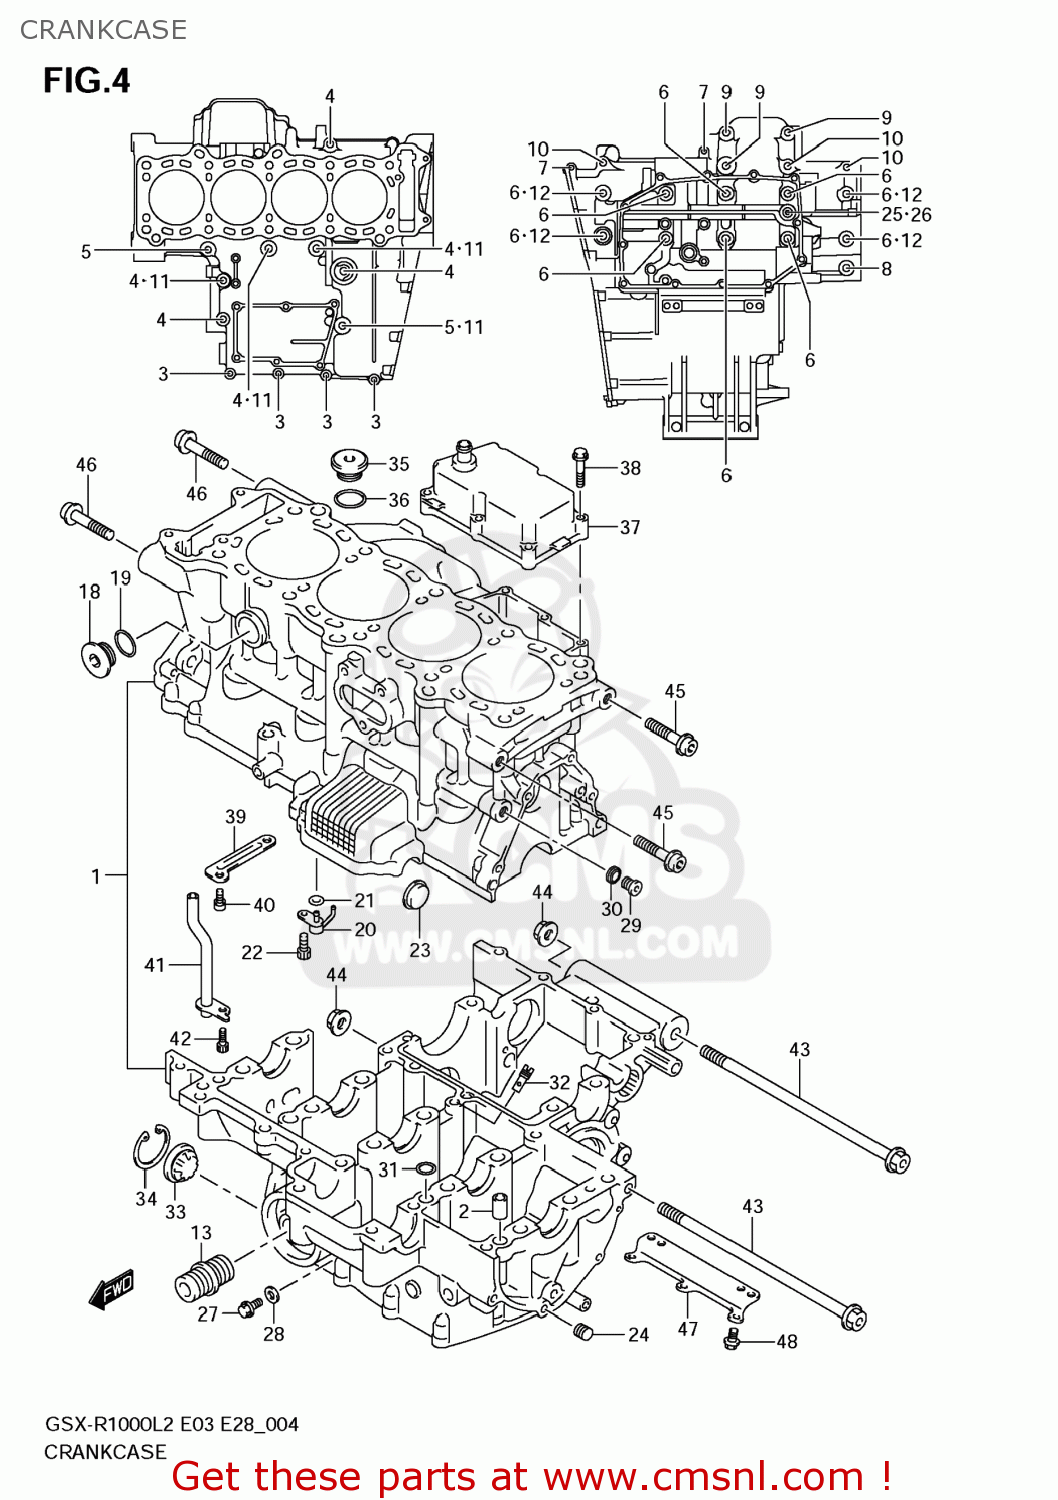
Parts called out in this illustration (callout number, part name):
1	CRANKCASE SET
2	PIN,CRANKCASE
3	BOLT
4	BOLT
5	BOLT
6	BOLT(9X95)
7	BOLT
8	BOLT
9	BOLT
10	BOLT
11	GASKET(8.2X14X1) (NAS)
12	GASKET(10.2X20X2).3 (NAS)
13	UNION,OIL STAND
14	O RING(D:3,ID:102)
15	BOLT(6X20)
16	BEARING,CRANK THRUST(GREEN)
17	BEARING,CRANK THRUST(RED)
18	PLUG,WATER JACKET
19	O RING(D:3.1,ID:19.4)
20	JET,PISTON COOLING
21	O RING(D:1.2,ID:4)
22	BOLT(6X12)
23	PLUG
24	PLUG(1/8PT,H:5.5)
25	PLUG(L:12)
26	GASKET(12.1X16.2X3.7) (NAS)
27	BOLT
28	GASKET(6.2X13X1.2) (NAS)
29	PLUG(10X10)
30	GASKET(10X14X3.6) (NAS)
31	O RING(D:1.9,ID:7.8)
32	JET(140)
33	LENS,OIL LEVEL CHECK
34	CIRCLIP
35	PLUG(26X9)
36	O RING(D:3.1,ID:22.7)
37	COVER,BREATHER
38	BOLT
39	PLATE,BREATHER OIL RETURN
40	BOLT(6X12)
41	PIPE,BREATHER OIL RETURN
42	BOLT
43	BOLT(12X220)
44	NUT
45	BOLT(10X45)
46	BOLT(10X55)
47	PLATE,CRANKCASE LWR
48	BOLT(6X10)
